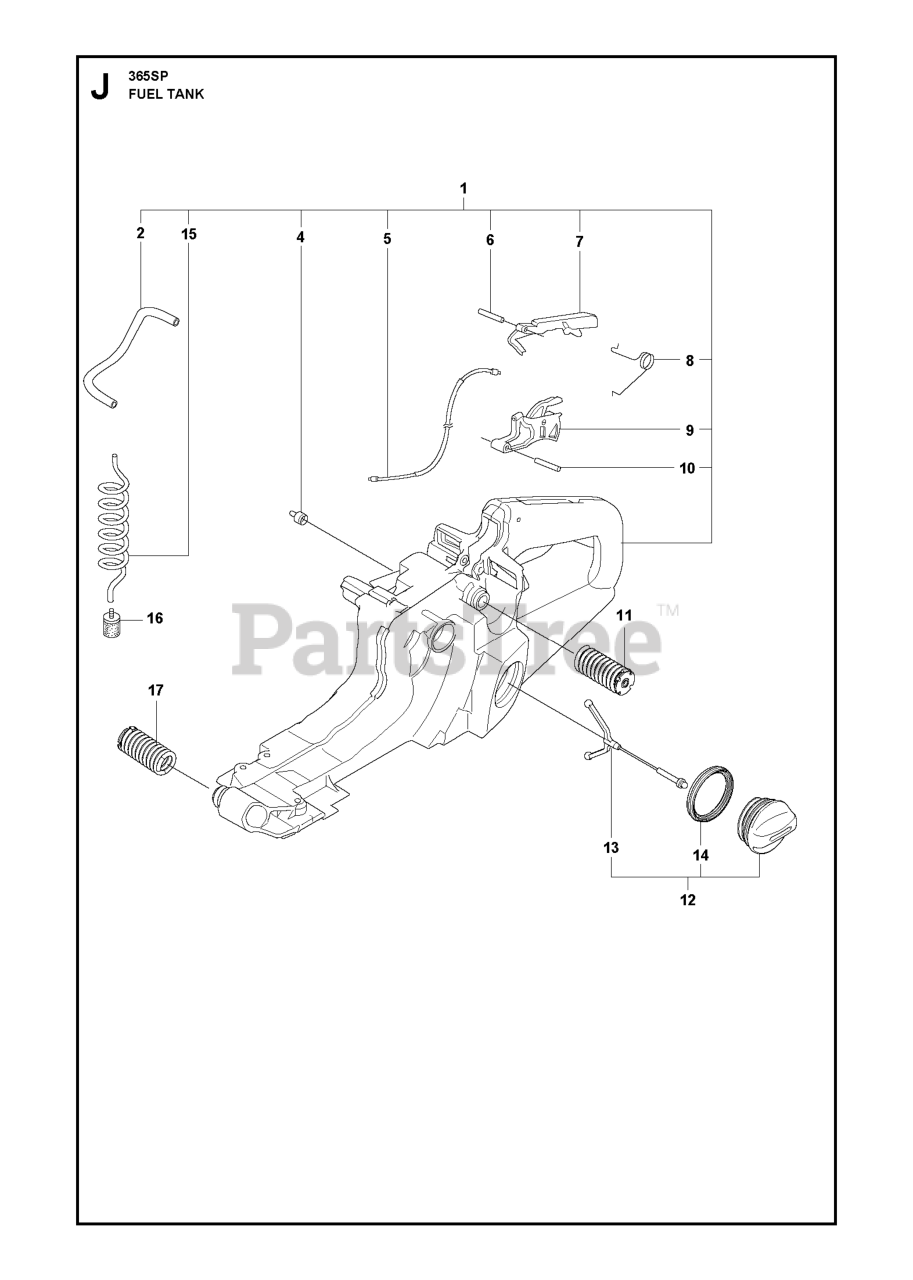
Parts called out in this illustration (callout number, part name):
2	FUEL HOSE STRAIGHT 105
3	CONNECTOR
4	FUEL TANK VENT
4	TANK VALVE
4	FILTER PLUG
6	PIN 3X25
7	THROTTLE CATCH
9	THROTTLE TRIGGER
10	PIN CPH8 4X20
11	ANTIVIBE MOUNT
15	FUEL HOSE SPIRAL 300
16	RP FUEL FILTER
17	Absorbers
